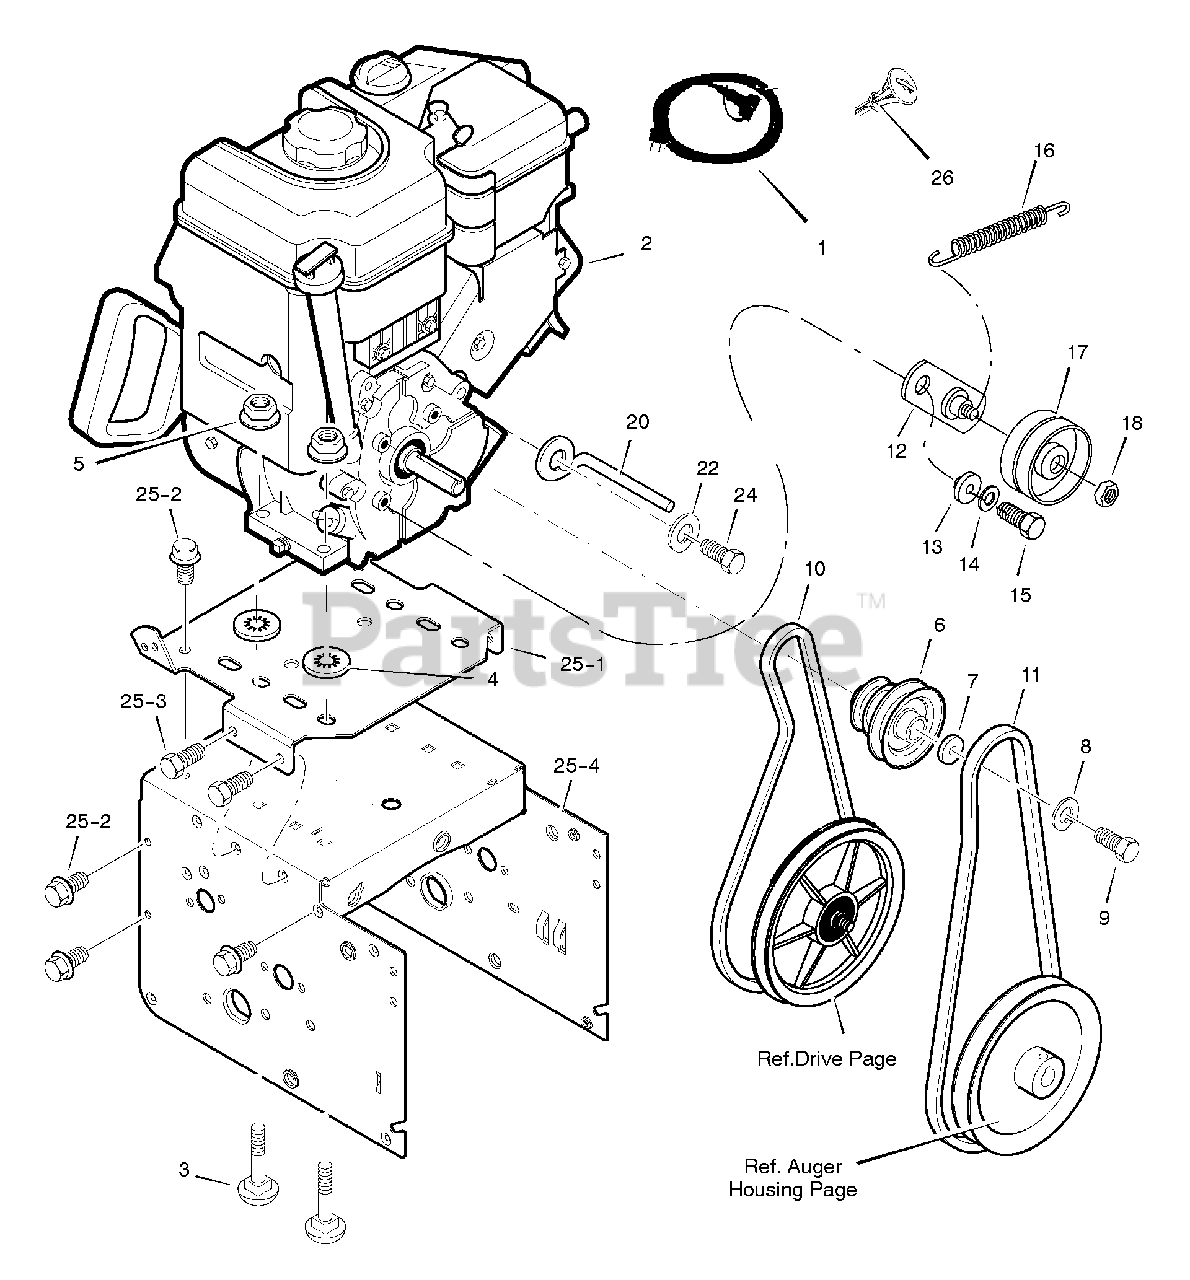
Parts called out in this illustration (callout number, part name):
1	CORD, STARTER
2	ENGINE
3	BOLT, CARRIAGE
4	RETAINER, PUSH
6	PULLEY, ENGINE
7	WASHER
8	WASHER
10	BELT, DRIVE V 3l
11	BELT, AUGER V 4L
12	BRACKET ASSEMBLY, IDLER
13	BUSHING, IDLER BRACKET
14	WASHER, SPLIT
15	SCREW 5/16-24 X 1.00
16	SPRING, IDLER TRACTION DRIVE
17	PULLEY, IDLER
18	NUT, JAM 3/8-16
20	GUIDE, ROD BELT
22	WASHER
25	FRAME ASSEMBLY
25-1	PLATE, ENGINE
25-2	SCREW
25-4	MOTOR BOX
26	KEY, BRIGGS ENGINE
